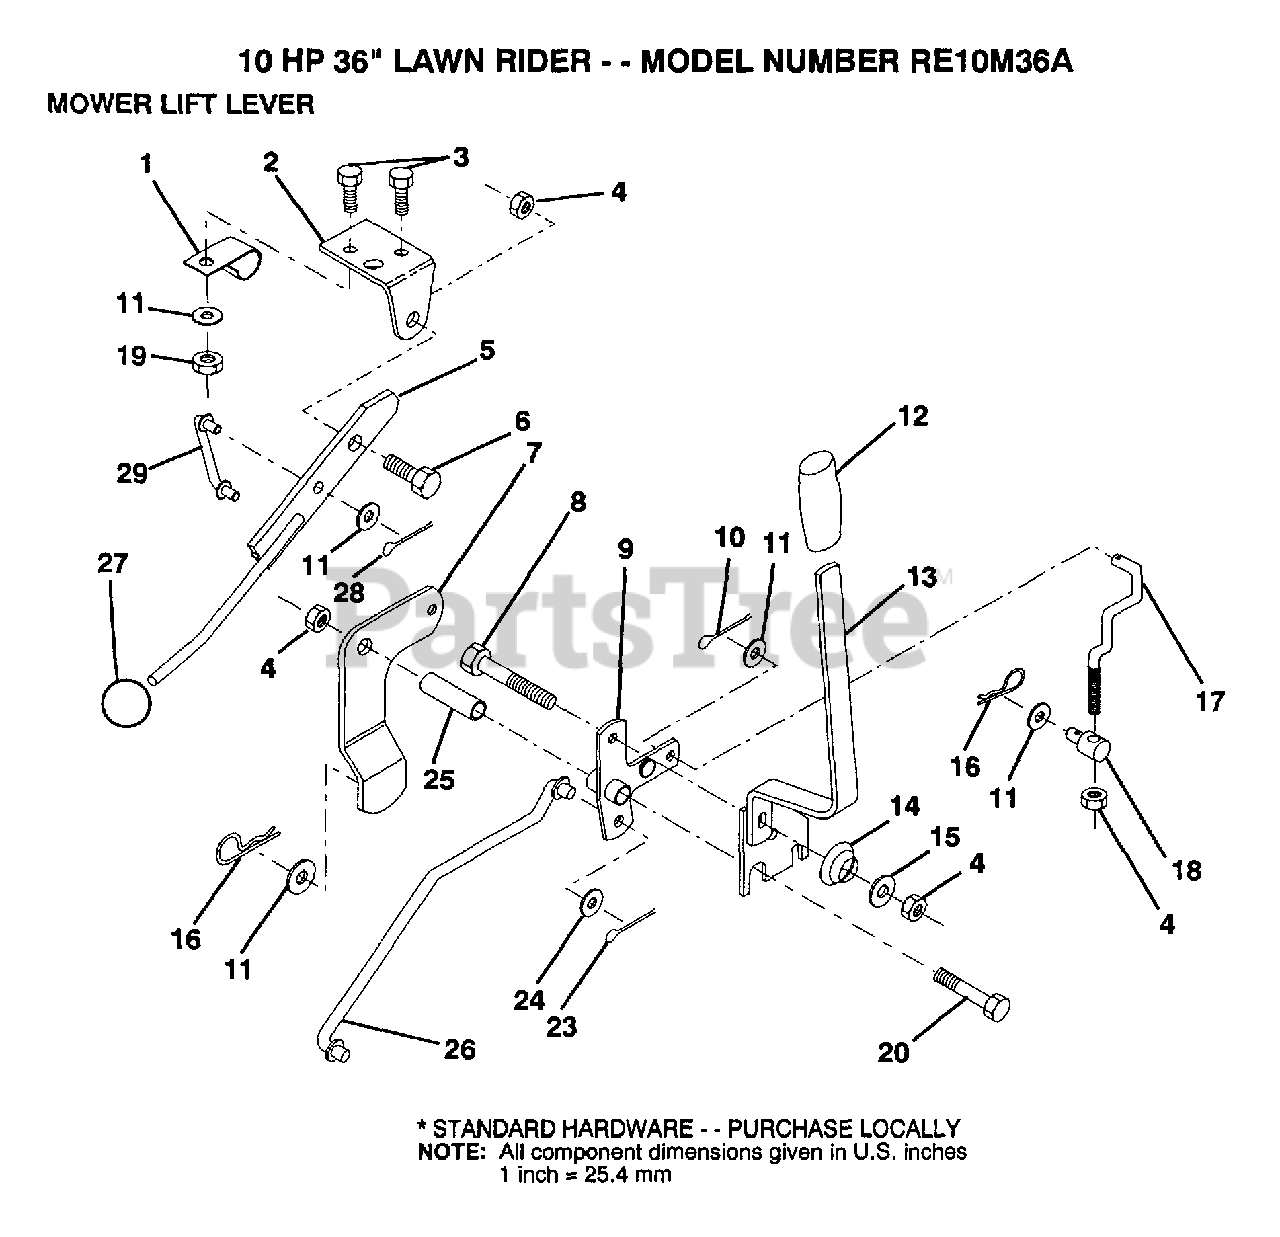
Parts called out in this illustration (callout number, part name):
1	"CLIP,INSULATOR"
2	BRKT CLUTCH
3	BOLT
5	CLUTCH LEVER AS
6	"BOLT, SHOULDER LT"
7	MWR CLUTCH ARM AS
8	BOLT
9	"BELLCRANK,LIFT"
10	COTTER PIN
11	WASHER
13	"HDLE,LIFT T"
14	SPRING COMPRESSIO
15	WASHER T
16	SPRING.RETAINER
17	"LINK,LIFT FRT"
18	TRUNION
20	BOLT
23	PIN COTTER 1/8
25	TUBE SPACER
26	"ROD,MOWER LIFT "
27	KNOB T(3/8 HOLE)
29	CLUTCH LINK
